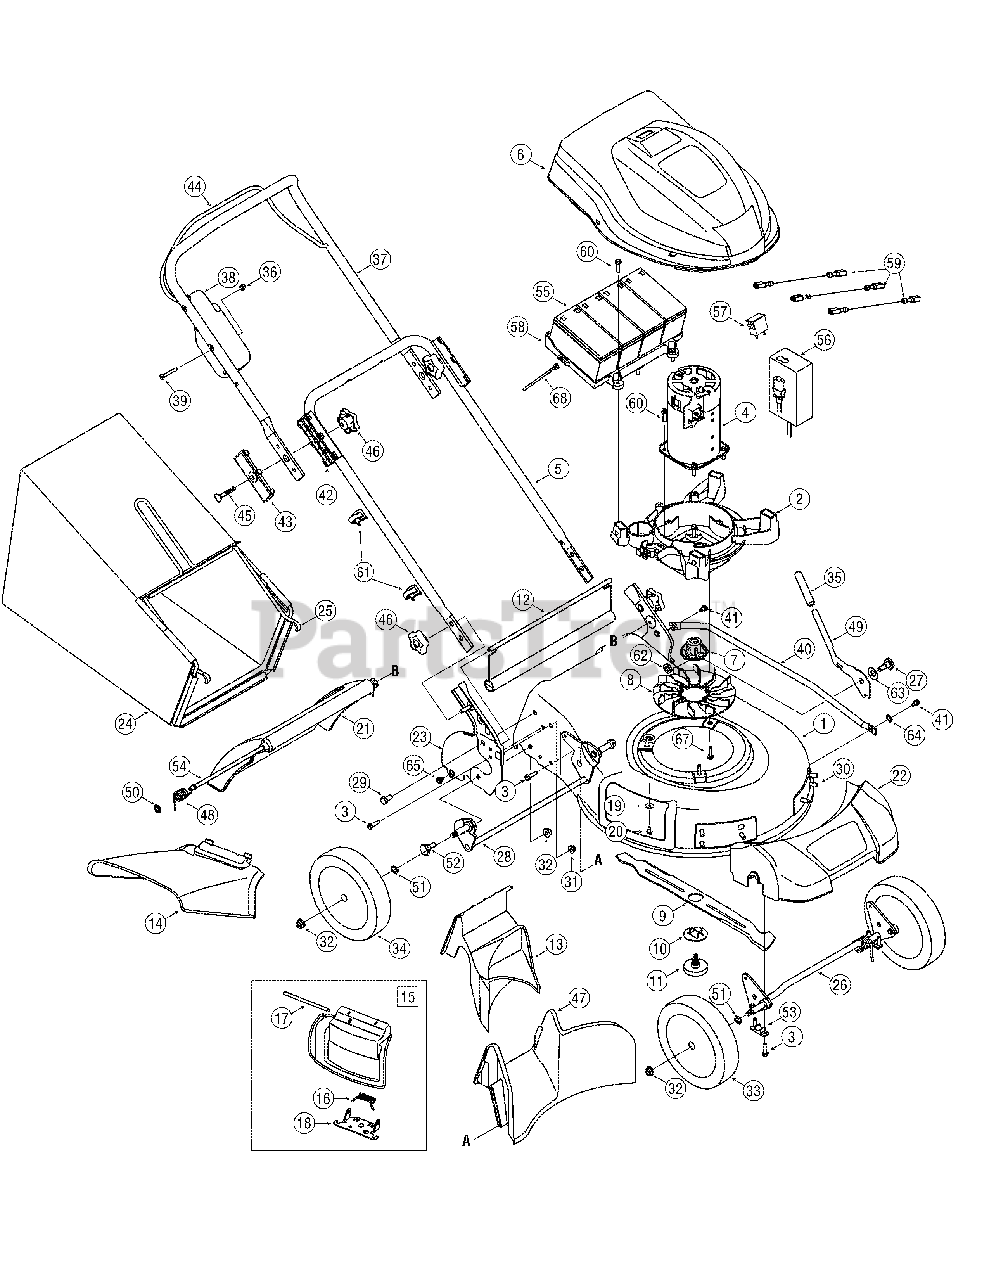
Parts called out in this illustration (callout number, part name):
3	Screw, 1/4-15 x 1.000
4	Motor, 48V
6	Battery Shroud
7	Blade Hub
8	Electric Fan
9	Mulching Blade
10	Blade Locking Plate
11	Blade Bolt Assembly
12	Trail Shield
13	Rear Mulch Plug
14	Side Discharge Chute
15	Mulch Plug
16	Torsion Spring
17	Hinge Pin
18	Chute Deflector Adapter
19	Beleville Washer
20	Screw
21	Rear Door
22	Front Cover
24	Grass Bag
27	Screw, Shoulder, .50 x .66
29	Hhcs, 5/16-18 x .625
30	Screw, 5/16-14 x .750
31	Nut, Flange Lock, 5/16-18
32	Nut, Flange Lock, 3/8-16
33	Front Wheel
34	Rear Wheel
35	Foam Grip
36	Nut, Hex Lock, 1/4-20
37	Upper Handle
38	Motor/Blade Control
39	Screw, Flat, 1/4-20 x 1.75
42	Lower Handle Insulator
43	Upper Handle Insulator
44	Motor/Blade Control Handle
45	Bolt Carriage, 5/16-18 x 2.50
46	Star Knob
47	Rear Baffle
48	Door Torsion Spring - RH
48	Door Torsion Spring - LH
49	Spring Lever
50	Nut, Speed
51	Washer, Wave, .510 x .750 x .017
52	Screw, Shoulder, .500 Dia. X .434
53	Bushing, Block, .505 Dia. X .62
54	Rear Door Pivot Rod
55	Battery, 12V
56	Battery Charger
57	Battery Level Indicator
58	Battery Tray
59	Battery Jumper
60	Screw, 1/4-15 x .750
61	Cable Guide
62	Spacer, .515 x 1.00 x .310 Lg.
63	Washer, Bell, .510 x 1.14 x .040
64	Washer, Wave, .390 x .825 x .016
65	Hubcap
66	Screw, #10-16 x .375
67	Screw, 5/16-12 x .750
68	Cable Tie
